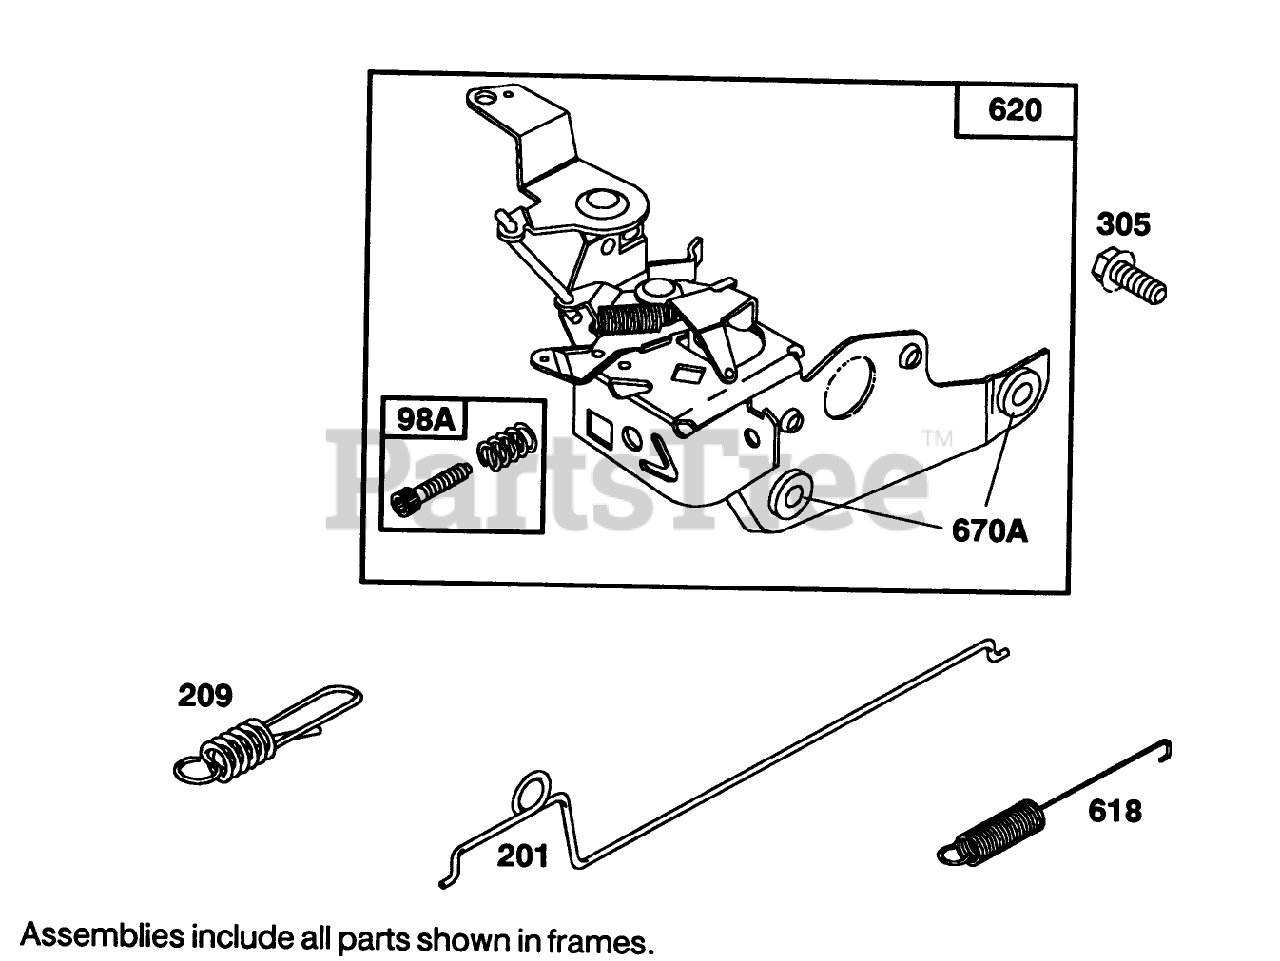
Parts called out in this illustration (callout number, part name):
98A	Screw Assy.
201	Link-Govemor
209	Spring-Govemor
305	Screw-Sem
618	Spring-Choke
620	Bracket Assembly
670A	Spacer
